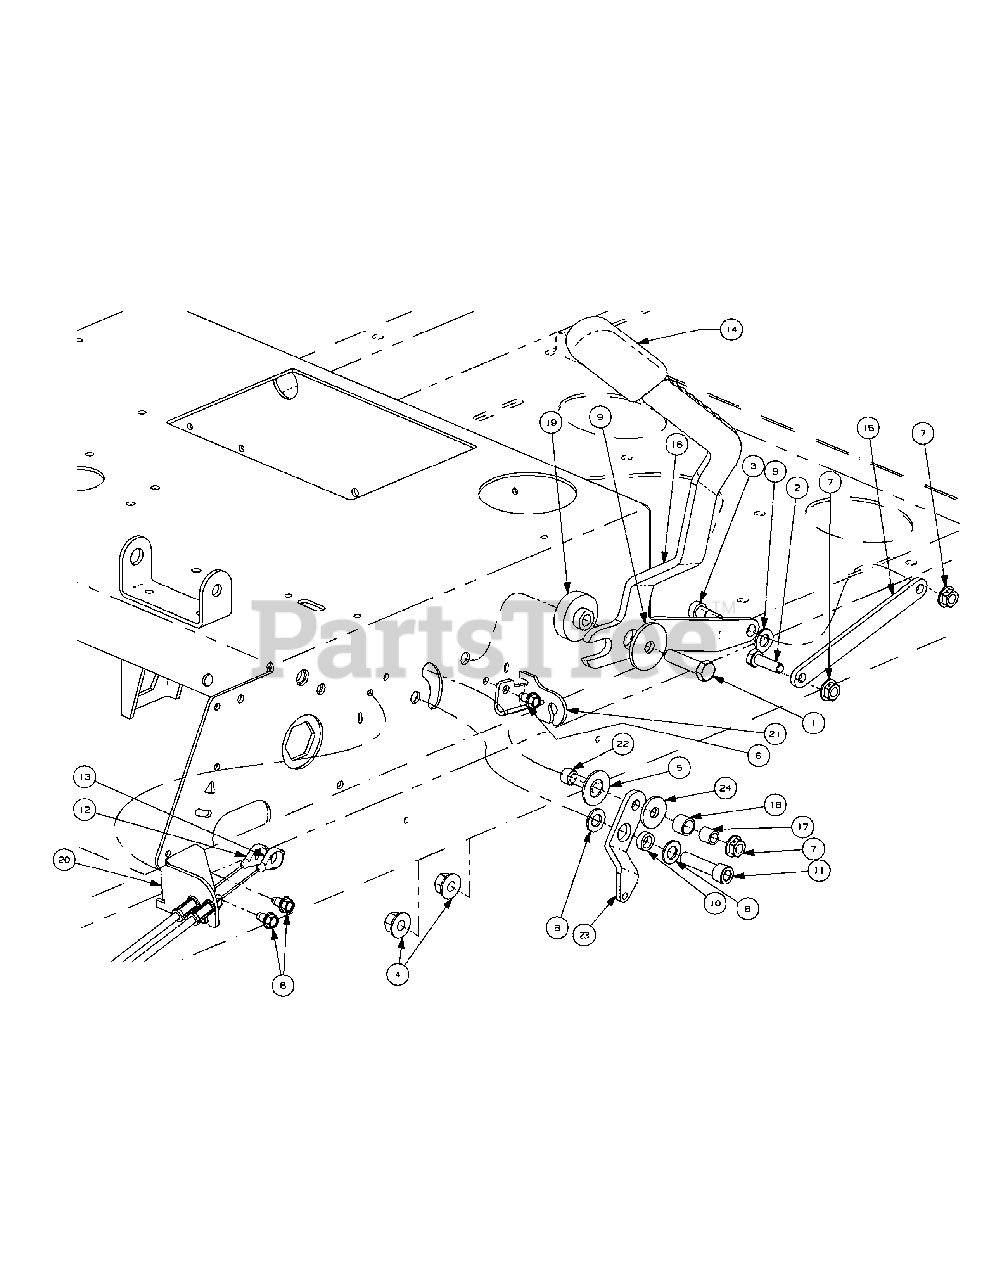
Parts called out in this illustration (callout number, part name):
1	Hex Head Cap Screw, 3/8-16 x 1.50
2	Hex Head Cap Screw, 5/16-18 x 1.00
3	Shoulder Bolt, 3/8 x 3/8
4	Hex Nut, 3/8-16 Flange Lock
5	Slide Washer
6	Screw, TT, 1/4-20, 0.5, Hex Index Washer
7	Nut, 5/16-18, Flange Lock
8	Washer, .375 x .738 x .063
9	Flat Washer, .390 x 1.5 x .134
10	Spacer, .380 x .563 x .196
11	Sockethead Capscrew, 3/8-16 x 1.50
12	Left Hand Brake Cable
13	Right Hand Brake Cable
14	Parking Brake Grip
15	Brake Link Plate
16	Brake Handle
17	Spacer, .322 ID x .438 OD x .44
18	Spacer, .442 ID x .563 OD x .405
19	Step Hub, .379 x 1.5 x .257/.400
20	Brake Cable Mounting Bracket
21	Brake Cable Mounting Bracket
22	Sockethead Capscrew, 5/16-18 x 1.00
23	Lockout Lever Plate
24	Washer, .345 x 1.00 x .100
